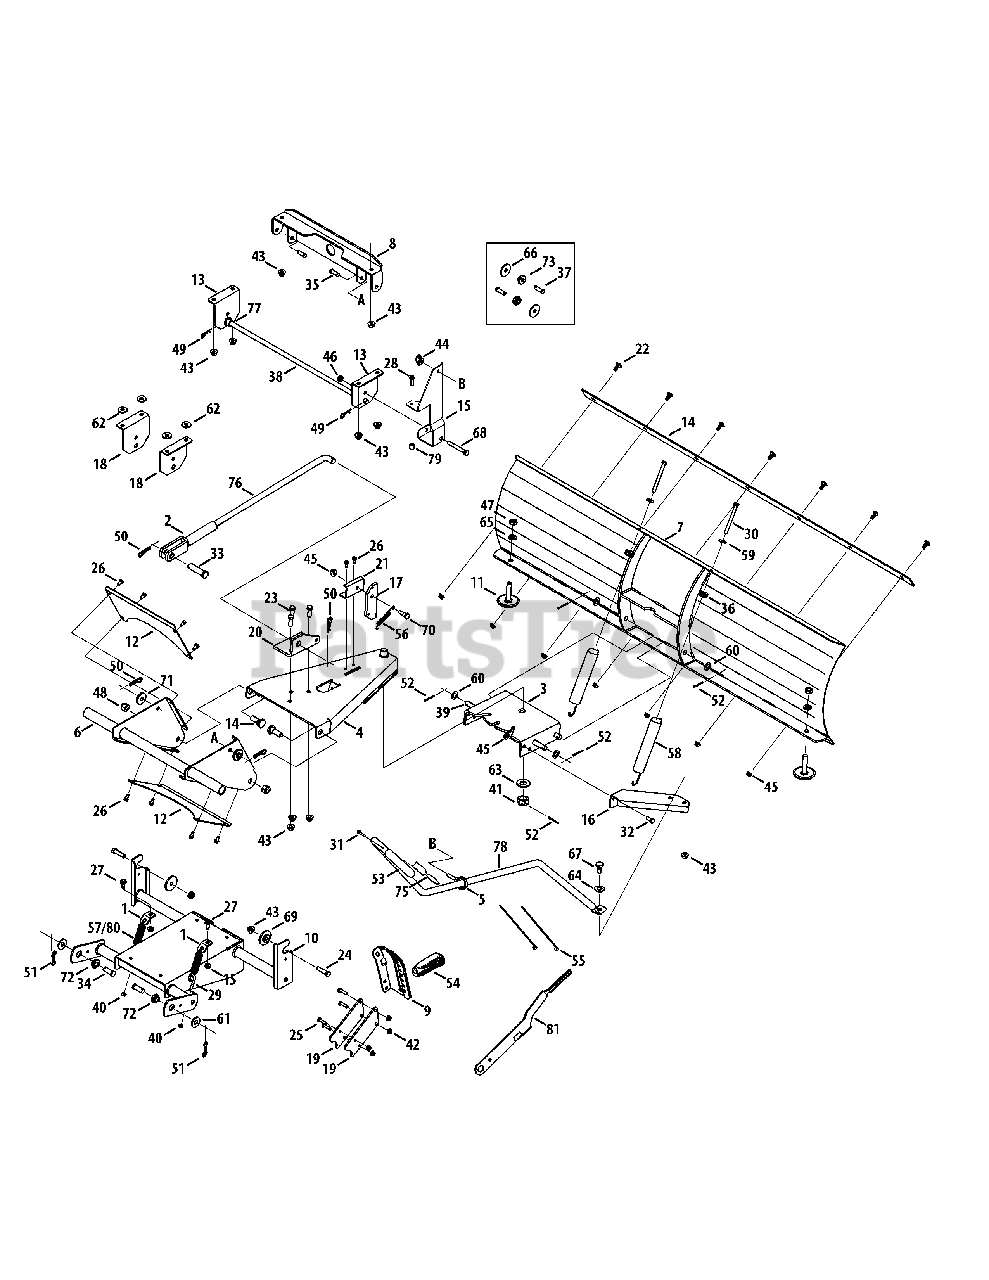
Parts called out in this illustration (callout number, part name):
1	Spring Mount Bracket
2	Clevis Adjustment Assembly
3	Blade Pivot Assembly
4	Blade Frame Assembly
5	Eyebolt Assembly
6	Bracket Assembly
7	52" Blade Assembly
8	Blade Mount Bracket Assembly
9	Blade Height Adj. Index Bracket
10	Lift Bracket Assembly
13	Mounting Bracket
14	52" Blade Scraper Plate
15	Handle Mount Bracket
16	RH Blade Adjustment Arm
17	Blade Lock Plate
18	Mount Bracket
19	Lift Arm Stiffener Bracket
20	Front Lift Bracket
21	Pivot Bracket
22	Carriage Bolt, 5/16-18 x .750
23	Hex Screw, 3/8-16 x 1.00
24	Hex Screw, 3/8-16 x 1.50
25	SCREW 1/4-20 X1.00 GR5
26	Hex Washer Screw, 1/4-20 x .50
27	Hex Washer Screw, 5/16-18 x .875
28	Hex Washer Screw, 1/4-20 x 1.000
29	Eye Bolt, 1/4-20
30	Hex Screw, 5/16-18 x 3.50
31	Machine Screw, #10-24 x 1.375
32	SCREW 5/16-18 x .75 GR5
33	Clevis Pin, .625 x 2.40
34	Clevis Pin, .500 x 1.25
35	Clevis Pin, .375 x .969
36	Spring Insert
37	Clevis Pin, 3/8 x 1.123
38	Rod, .50 x 22.65
39	Rod, .50 x 10.428
40	Nut, 1/4-20
41	Slotted Nut, 3/4-16
42	Flange Lock Nut, 1/4-20
43	Flange Lock Nut, 3/8-16
44	Wing Nut, 5/16-18
45	HEX FLANGE NUT
46	Jam Lock Nut, 3/8-16
47	Jam Nut, 1/2-13
48	Hex Lock Nut, 1/2-13
49	Click Pin, .092 x 1.64
50	Cotter Pin, .125 x 1.75
51	Bow-Tie Cotter Pin
52	Cotter Pin, 1/8 x 1.25
53	Foam Grip
55	Cable Tie, 3/16 x 7.4
56	Extension Spring, .38 x 3.25
58	Extension Spring, 1.25 x 6.7
59	Flat Washer, .349 x .879 x .063
60	Flat Washer, .530 x .930 x .050
61	Flat Washer, .531 x 1.250 x .100
62	Flat Washer, .385 x 1.000 x .135
63	Flat Washer, .760 x 1.500 x .120
64	Flat Washer, .570 x 1.120 x .062
65	Lock Washer, 1/2
66	Flat Washer, .406 x 1.500 x .105
67	SHOULDER SCREW .498 DIA x .340
68	Shoulder Bolt, 3/8-16 x .500 x 2.38
69	Shoulder Spacer, .8840 x .190
70	Shoulder Screw, 5/16-18 x .405 x .435
71	Shoulder Spacer, 1.375 x .380 x .183
72	Shoulder Spacer, .50 x .75 x .170
73	Shoulder Spacer, .375 x .75 x .170
74	Shoulder Screw, 1/2-13 x .625 x .36
75	Blade Release Cable
77	Flange Bearing, .503 x .75
78	Blade Adjust Handle
79	Spacer, .258 x .50 x .50
81	Lift Handle
